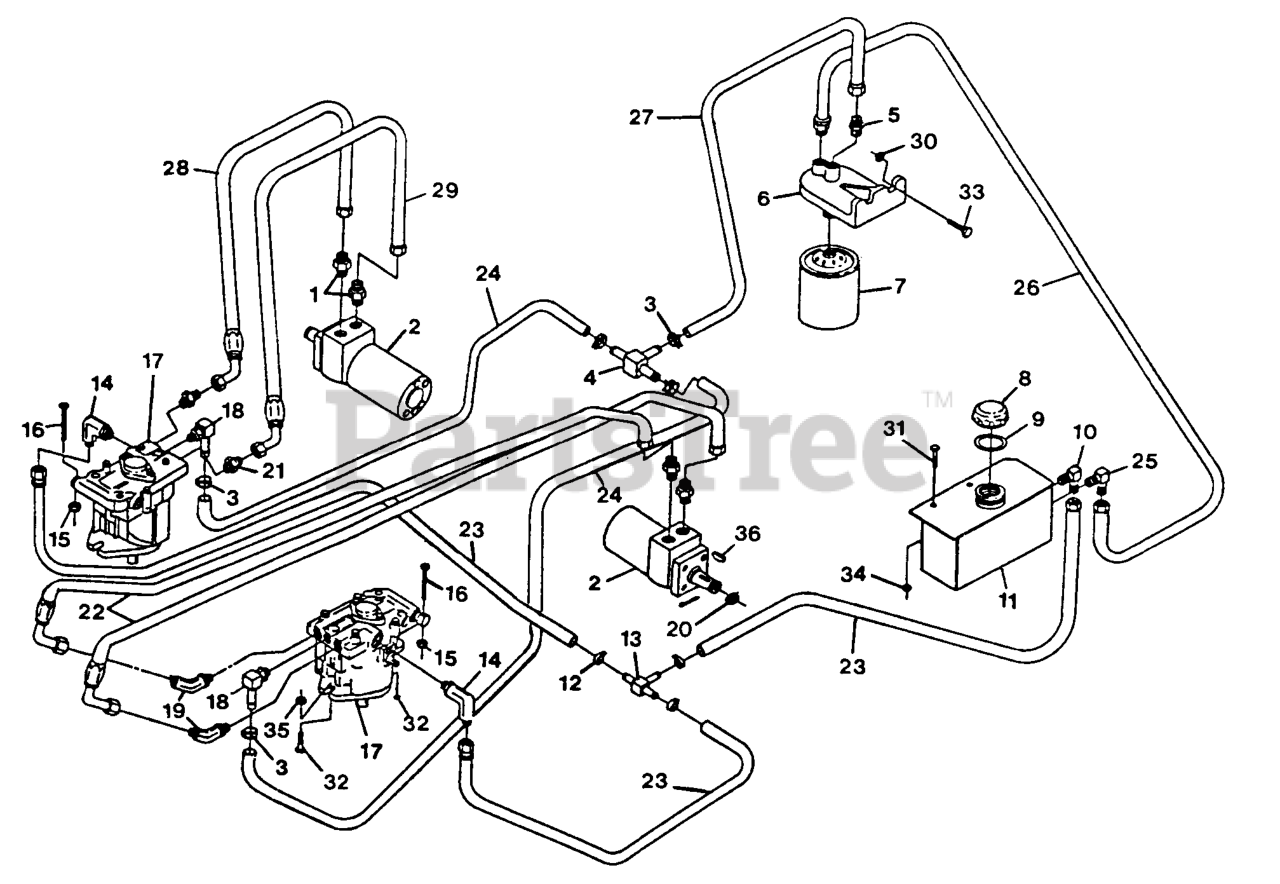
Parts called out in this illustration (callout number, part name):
1	FITTING-STRAIGHT
2	HYD MOTOR ASM
3	CLAMP-HOSE
4	FITTING-TEE, HOSE
5	FITTING-STRAIGHT
8	CAP
9	GASKET-CAP, TANK
10	FITTING-ELBOW
12	CLAMP-HOSE
13	FITTING-TEE, HOSE
14	FITTING-90 DEG
18	FITTING
19	FITTING-HYD, 45 DEG
21	FITTING-STRAIGHT
22	HOSE,HIGH PRESSURE
23	ASM,HOSE CASE DRAIN
24	HOSE,LO PRESSURE
25	FITTING-ELBOW
26	ASM,HOSE LO PRESSURE
27	ASM,HOSE CHARGE LINE
29	HOSE-PRESSURE, HIGH
36	KEY-WOODRUFF
